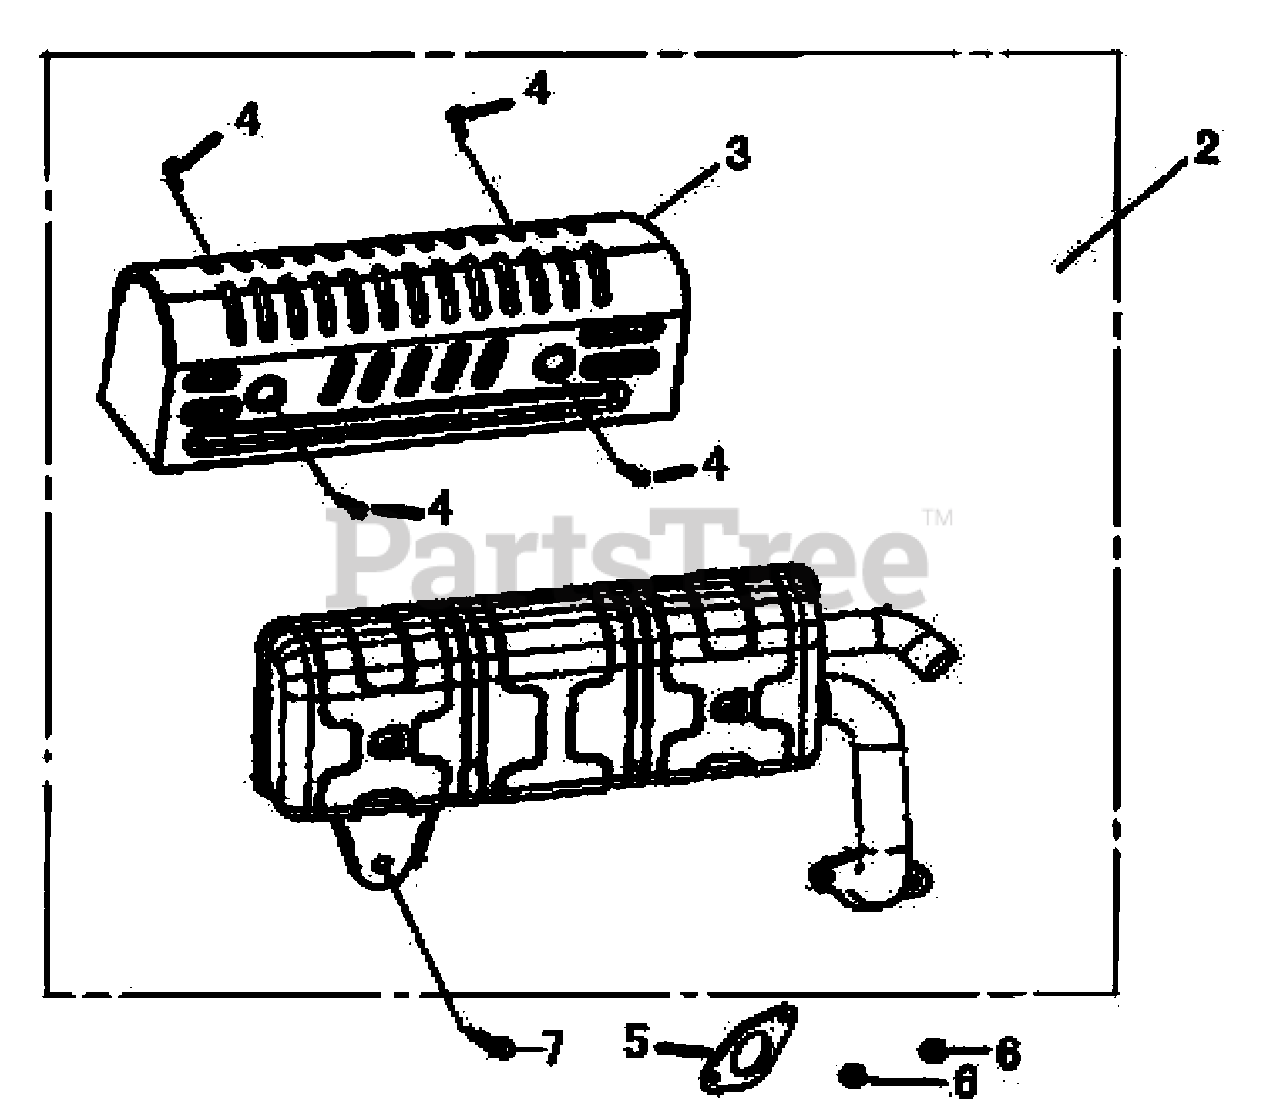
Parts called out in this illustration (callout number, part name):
2	MUFFLER ASSY.
3	PROTECTOR, MUFFLER
4	BOLT, FLANGE
5	GASKET, MUFFLER
7	BOLT, FLANGE
